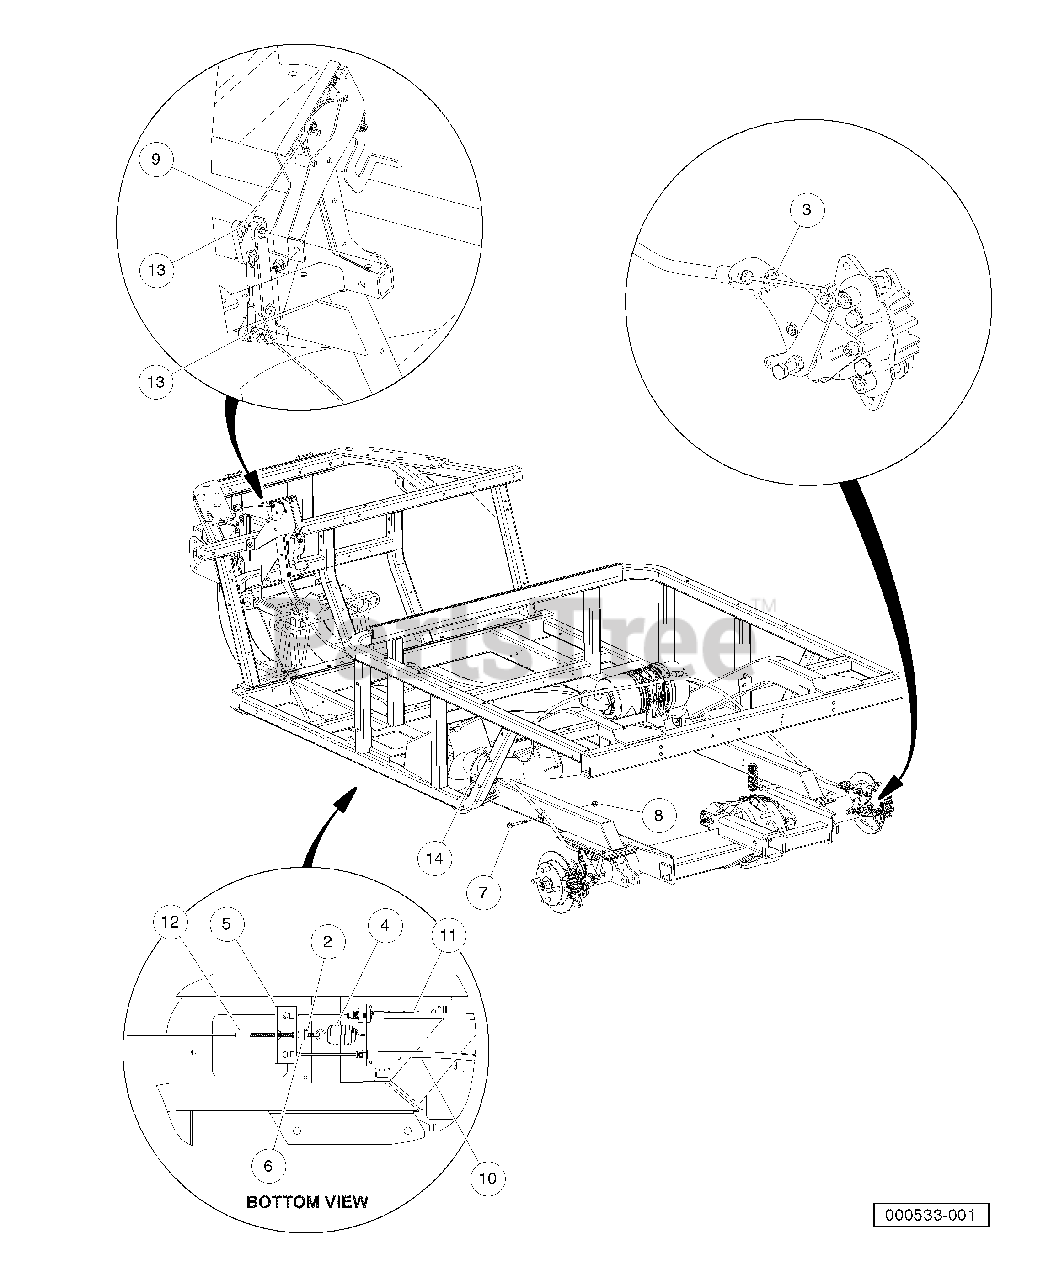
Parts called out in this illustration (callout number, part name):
1	Instl, Brake, Park, AWD
2	Nut, 5/16-24 Hex
3	E-Clip, 1/2
4	Spring, Brake Return
5	Equalizer Bracket
6	Nut, 5/16-24 Hex Cone
7	Bolt Flanged Head, M8 X 1.25 X 65
8	Lock Nut, Flg M8 X 1.25 Nylon
9	Cable, Crank, Bell, Front
10	Cable, Noncoated, Pbrake, Left
11	Cable, Noncoated, Pbrake, Rght
12	Cable, Crank, Bell, Main
13	Pin, 3/32 X 1.00 Sq Cut Cotter
14	Tie Wrap, 11" Nylon
